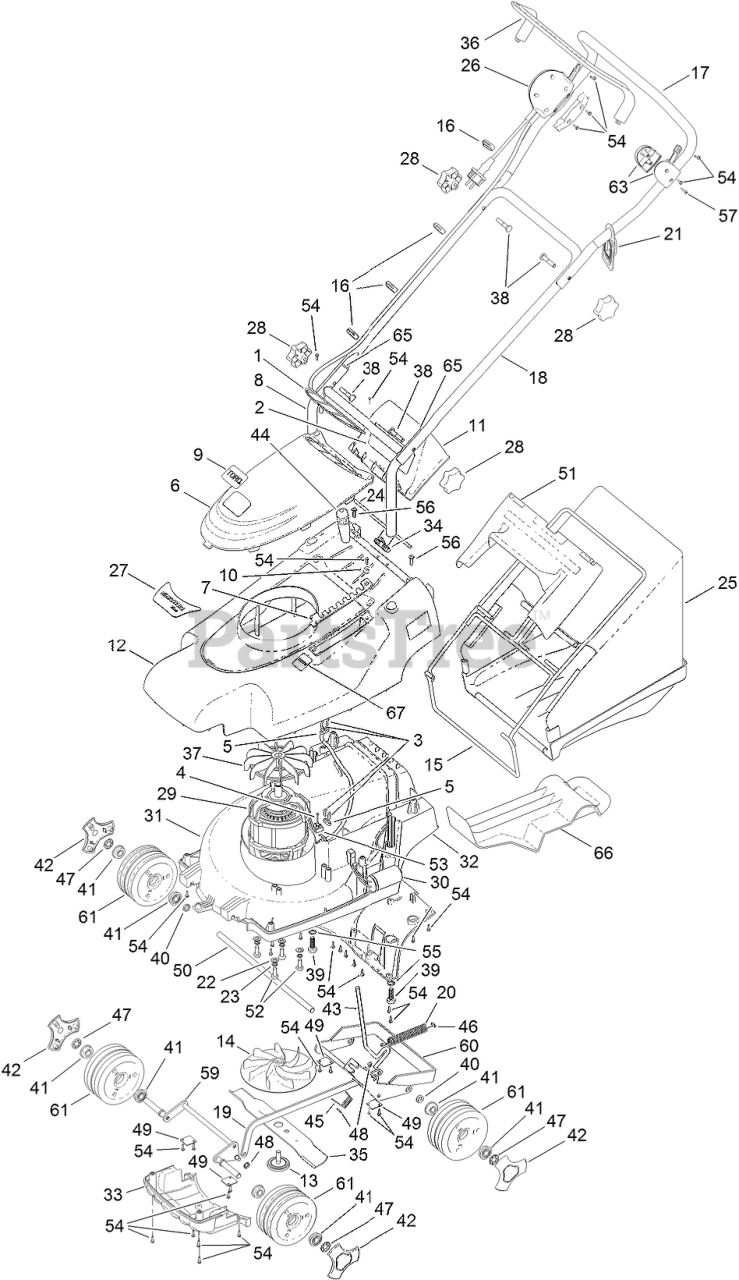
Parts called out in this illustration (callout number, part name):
1	VENT MESH ASM
2	DECAL-SAFETY ELECTRIC (CHINA ONLY)
5	CLAMP-CABLE
6	COVER-MOTOR
7	PLATE-HOC
8	HANDLEBAR-LOWER
9	PLATE-LOGO, TORO
10	COVER-SCREW, HOC
11	DEFLECTOR-REAR
12	COVER-TOP
13	BOLT-FIXING, CUTTERBAR (NYLON)
14	CARRIER-CUTTERBAR
15	FRAME-GRASSBAG
16	CLIP-CABLE
17	HANDLEBAR-UPPER
18	HANDLEBAR-MIDDLE
19	ROD-CONNECTING
20	SPRING-BALANCE, COUNTER
21	CLEAT-CABLE
22	Sealant-Liquid
23	WASHER-SPRING
24	ROD-DEFLECTOR
25	GRASSBAG
26	SWITCH AND LEAD ASM
28	KNOB-HANDLEBAR
29	MOTOR
30	CAPACITOR
31	UNDERDECK
32	THROWPLATE
34	SPRING-DEFLECTOR
35	CUTTERBAR
36	ARM-BAIL
37	FAN-TOP, MOTOR
38	BOLT-HANDLEBAR
39	BOLT-PLASTIC
40	SPACER-WHEEL, REAR
41	BEARING-WHEEL
42	CAP-HUB
43	LEVER-HOC
44	KNOB-HOC
45	SPRING-HOC
46	PIN-SPRING, HOC
47	WASHER-STARLOCK
48	WASHER-STARLOCK, 8mm
49	PLATE-PIVOT, AXLE
50	ROD-AXLE, REAR
51	TOP-GRASSBAG
52	BOLT-MOTOR
53	BLOCK-TERMINAL
55	WASHER
56	SCREW-PPH, THREAD FORMING
57	SCREW-PPH
59	FRONT AXLE ASM
60	REAR AXLE ASM
61	WHEEL ASM
63	MOUNT BAIL ARM ASM
65	PLUG-TUBE
66	PLUG-MULCHING
67	DECAL-HOC
